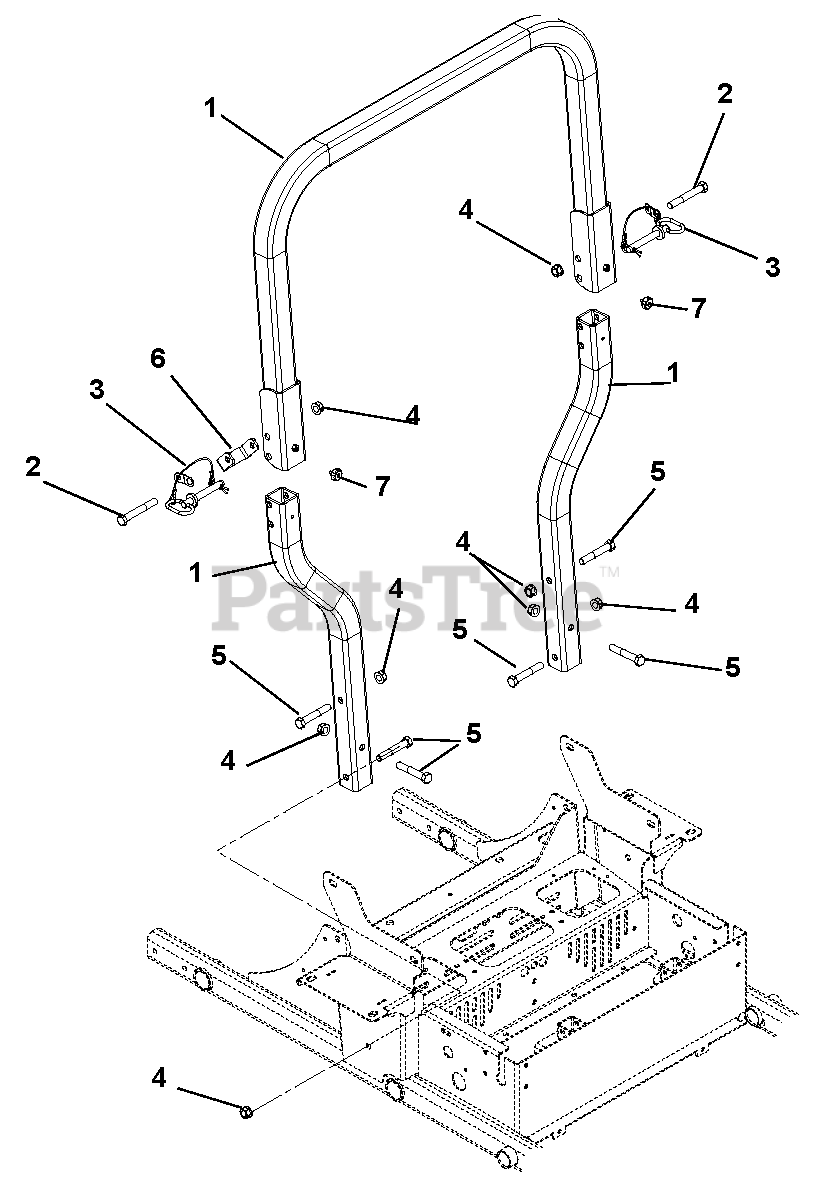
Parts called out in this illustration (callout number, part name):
1	ROPS, PT200 Replacement
2	Bolt, Hex .50-13 x 3.50 Grade 5
3	Assembly, ROPS Pin/Lanyard
4	Nut, Locking Top Flange .50-13
5	Bolt, Hex .50-13 x 3.00 Grade 5
6	Bracket, ROPS Stop, Pro-Turn
7	Knob, Round .312-18 x .750
